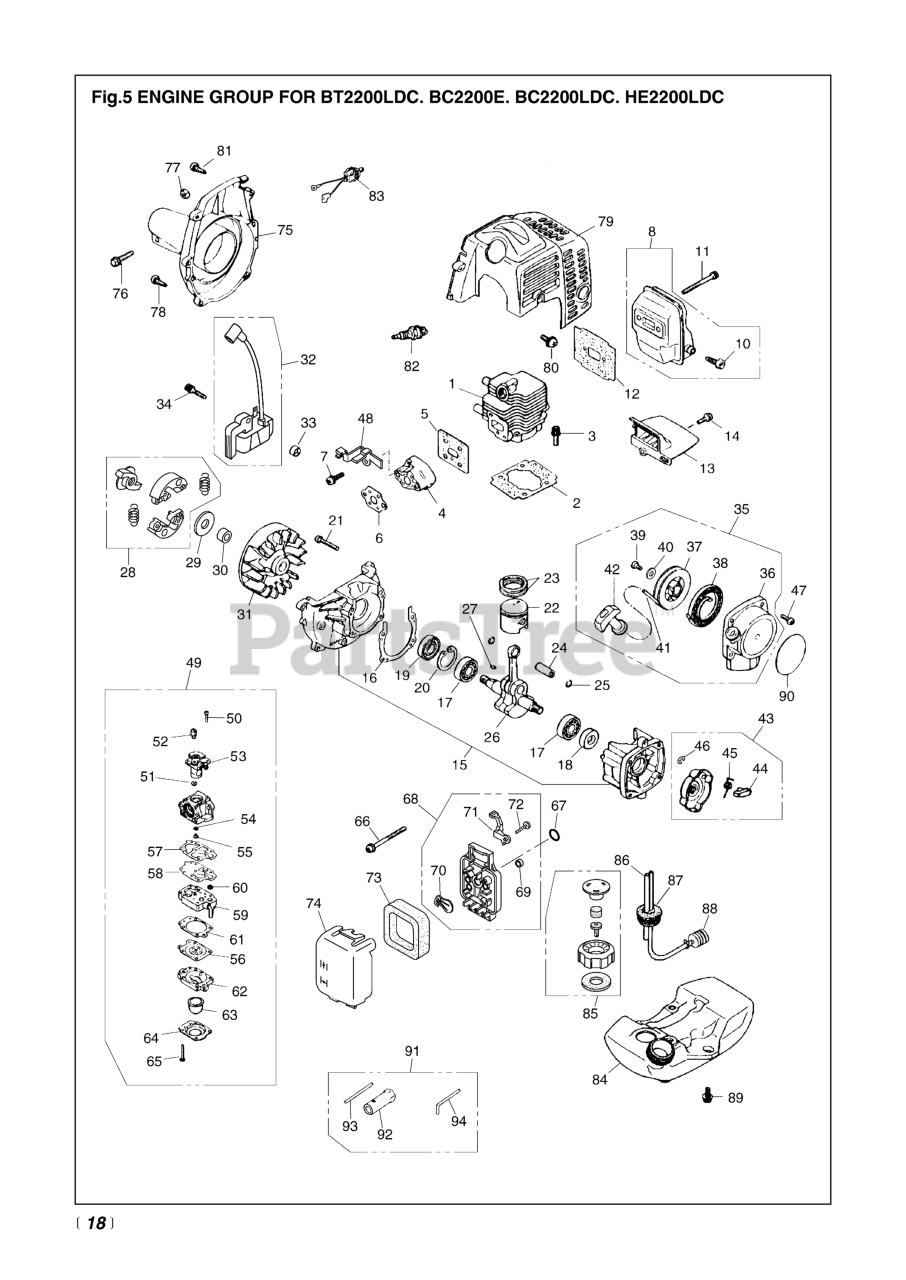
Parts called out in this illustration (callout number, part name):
1	CYLINDER
3	BOLT, M5 X 22
4	INSULATOR
8	MUFFLER ASSY (RPLS 5501- )
10	ARRESTER
12	GASKET, MUFFLER
13	PLATE, MUFFLER
15	CRANKCASE (NLA)
17	BEARING
18	SEAL, OIL (RPLS 1100-21210)
19	SEAL
20	RING
21	BOLT, M5 X 30
22	PISTON (REPLACES 1140-41110)
23	RING, PISTON (RPLS 1850-41210)
24	PIN, PISTON 5x8x26
25	RING
26	CRANKSHAFT COMP.
27	KEY
31	ROTOR (RPLS -71110)
32	COIL
33	SPACER
40	WASHER (USE 181741)
46	RING, SNAP, M4
51	RING
52	SWIVEL
53	VALVE ASSY
54	O-RING
55	JET
56	DIAPHRAGM (USE 4810-81260)
57	GASKET, PUMP
58	DIAPHRAGM
59	BODY ASSY
61	GASKET, DIAPHRAGM
62	BODY
63	PUMP
64	COVER
65	SCREW
69	SLEEVE
70	PLATE, CHOKE
71	LEVER CHOKE
72	SCREW
76	BOLT, M6x35 (RPLS -50635)
77	NUT M6
83	SWITCH COMP
91	TOOL SET
94	BAR
